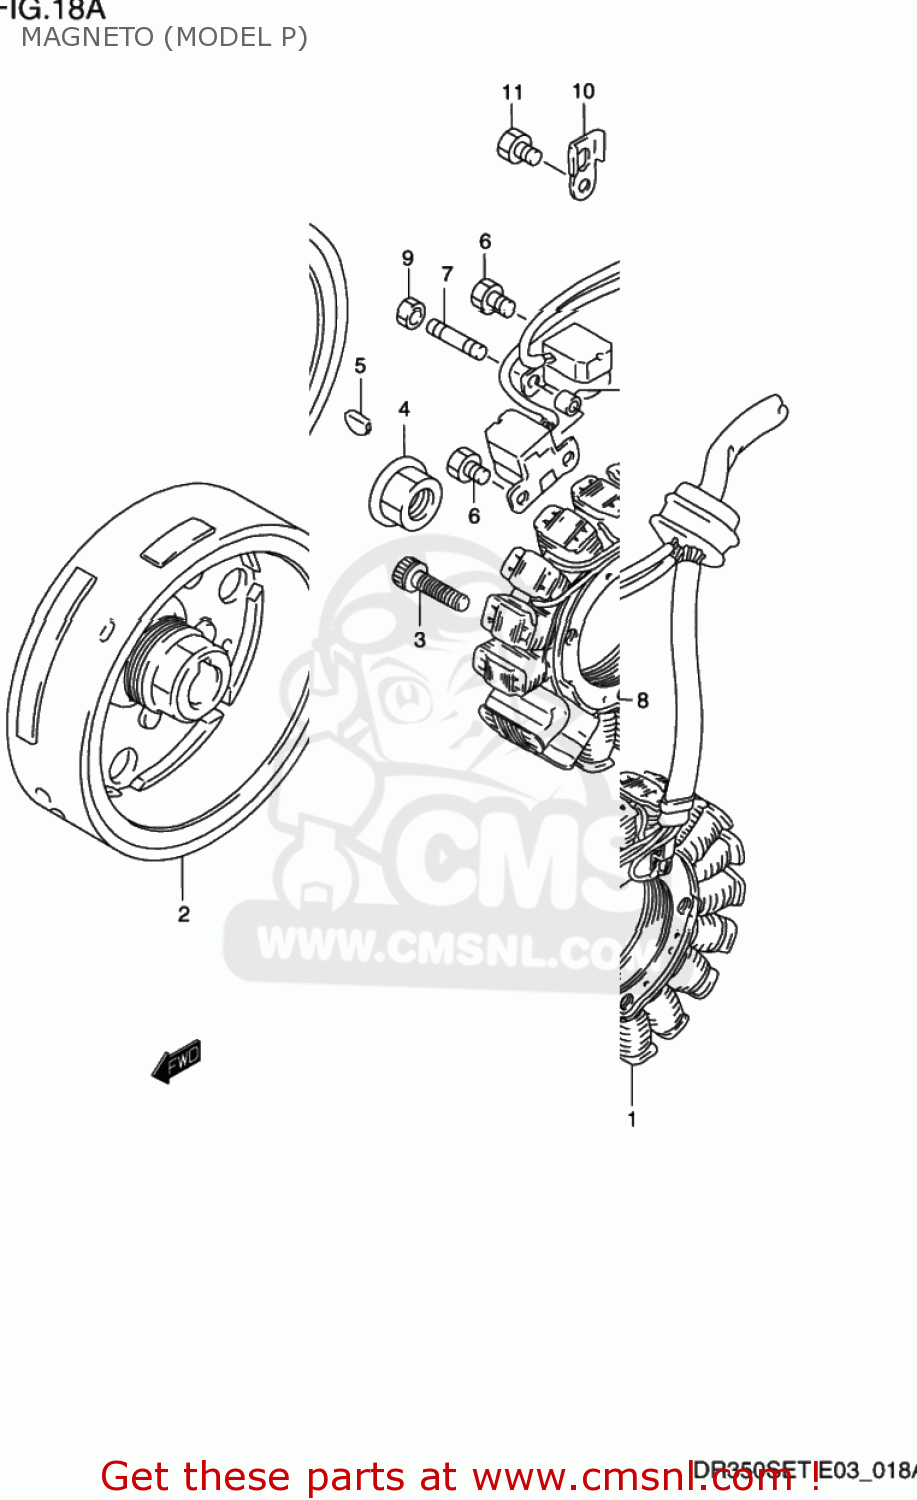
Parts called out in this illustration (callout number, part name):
1	STATOR ASSEMBLY
2	ROTOR
3	BOLT
4	NUT
5	KEY
6	BOLT(5X10)
7	BOLT,STUD(5X18)
8	SPACER (5.5X9.5X6.5)
9	NUT 5MM
10	CLAMP,GENERATOR LEAD WIRE
11	BOLT(5X10)
